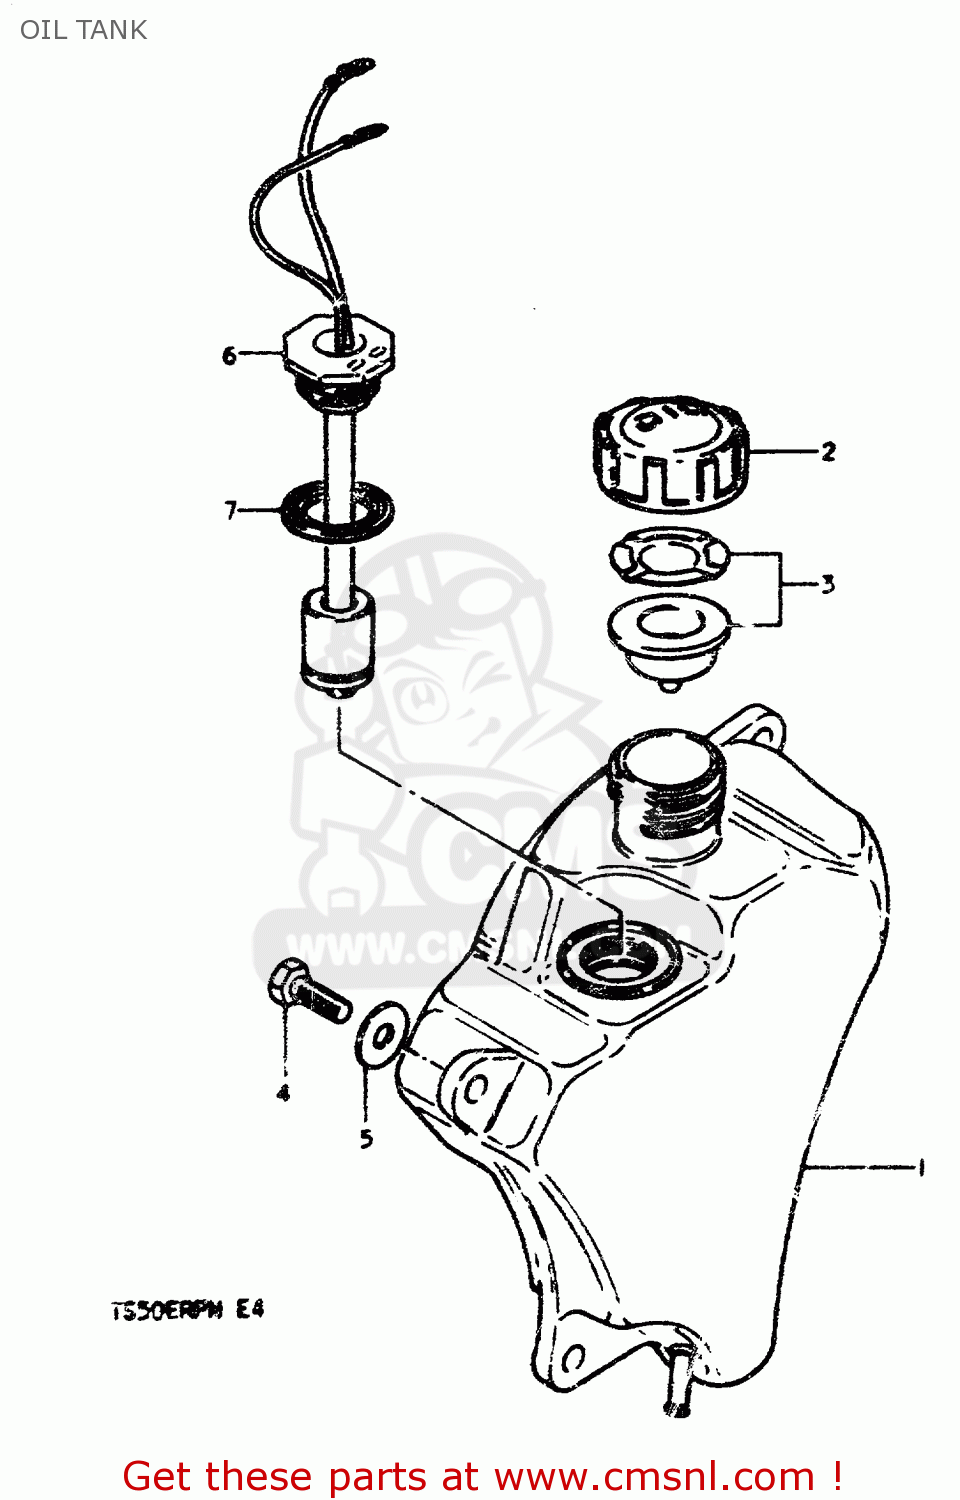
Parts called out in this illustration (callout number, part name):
1	TANK, OIL
2	CAP,OIL TANK
3	GASKET SET (NAS)
4	BOLT, UPPER
5	WASHER
6	SWITCH, OIL LEVEL
7	GASKET (NAS)
